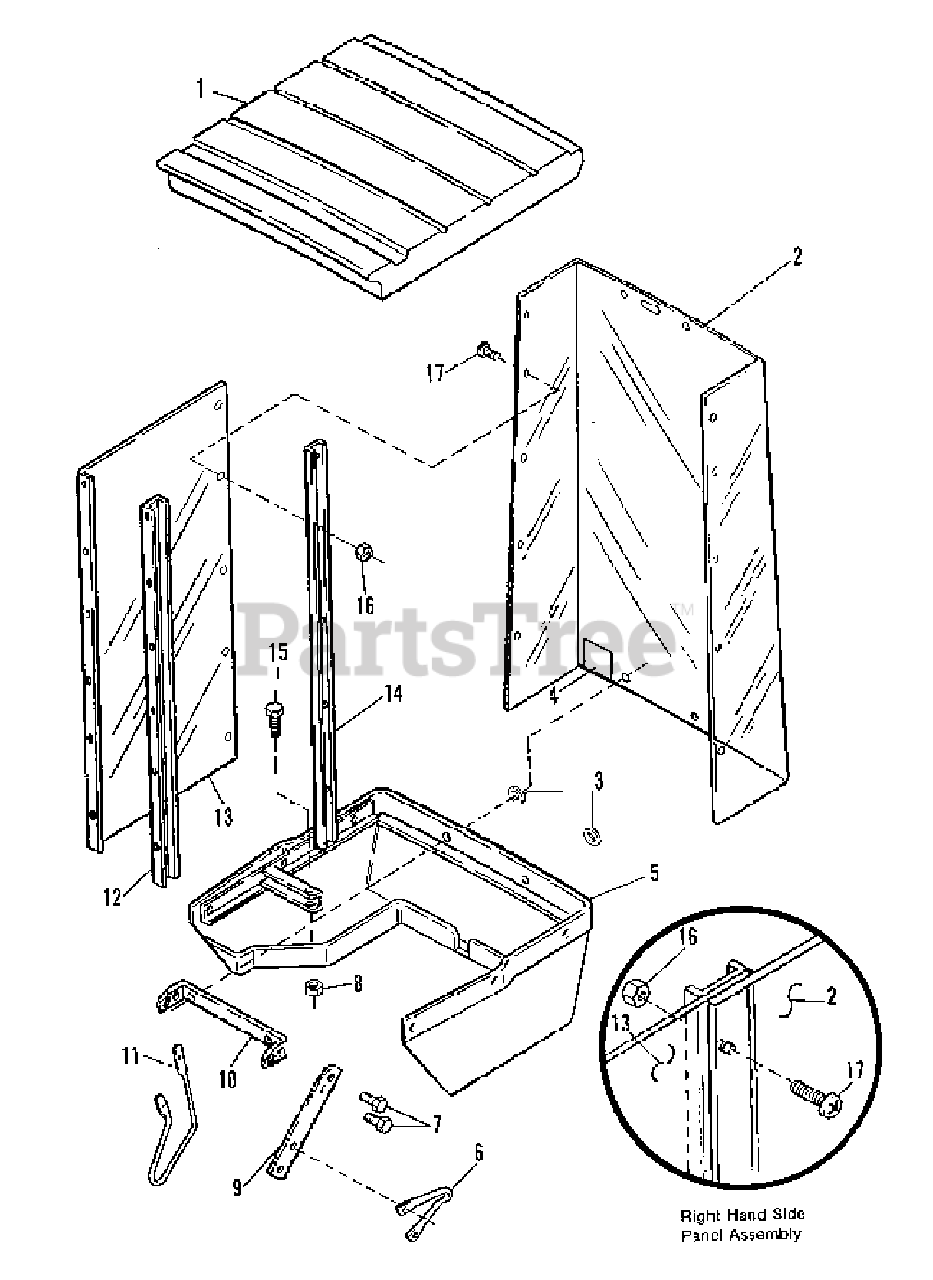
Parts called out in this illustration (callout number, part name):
1	COVER, Top
2	PANEL, Front
3	WASHER, Flat, 9/32
4	DECAL, Cleaning Instructions
5	SHROUD, Lower
6	GUIDE, Rope
7	CAPSCREW, Hex Head, 1/4-20 x 3/4
8	LOCKNUT, Nylon, 5/16-18
9	SUPPORT, Side
10	SUPPORT, Front
11	ROD, Skid
12	CHANNEL, Side
13	PANEL, Side
14	SUPPORT ASSEMBLY, L.H.
15	CAPSCREW, Hex Head, 5/16-18 x 1-3/4
16	LOCKNUT, Nylon, 1/4-20
17	SCREW, Phil. Truss Head, 1/4-20 x 3/4
